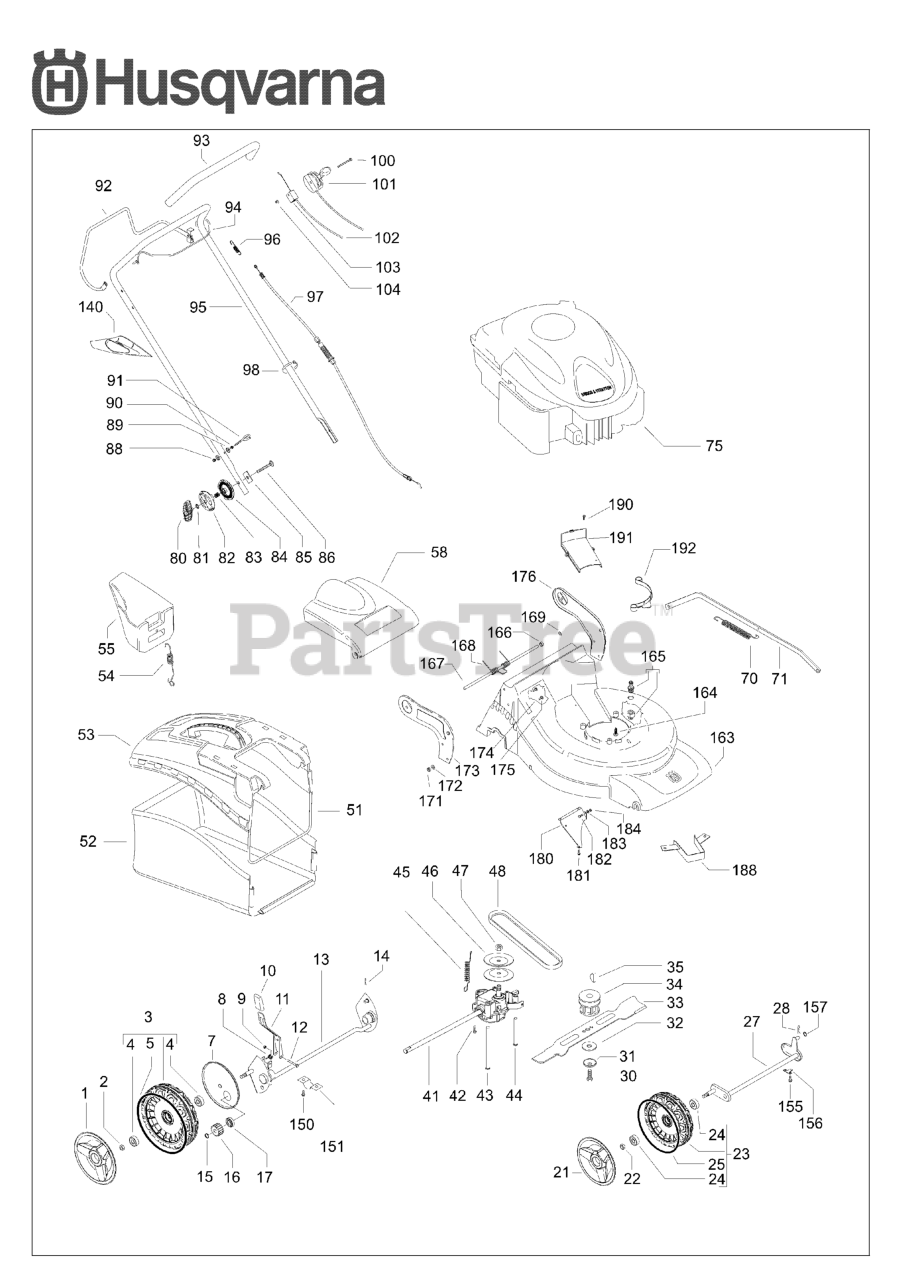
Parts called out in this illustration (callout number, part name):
11	LIFTING LEVER ASSY FOR REAR AX
51	FRAME 51 CAST
53	COVER HARD TOP
58	DEFLECTOR 51 CAST ORANGE
102	BRAKE WIRE
168	SPRING 51 CAST
